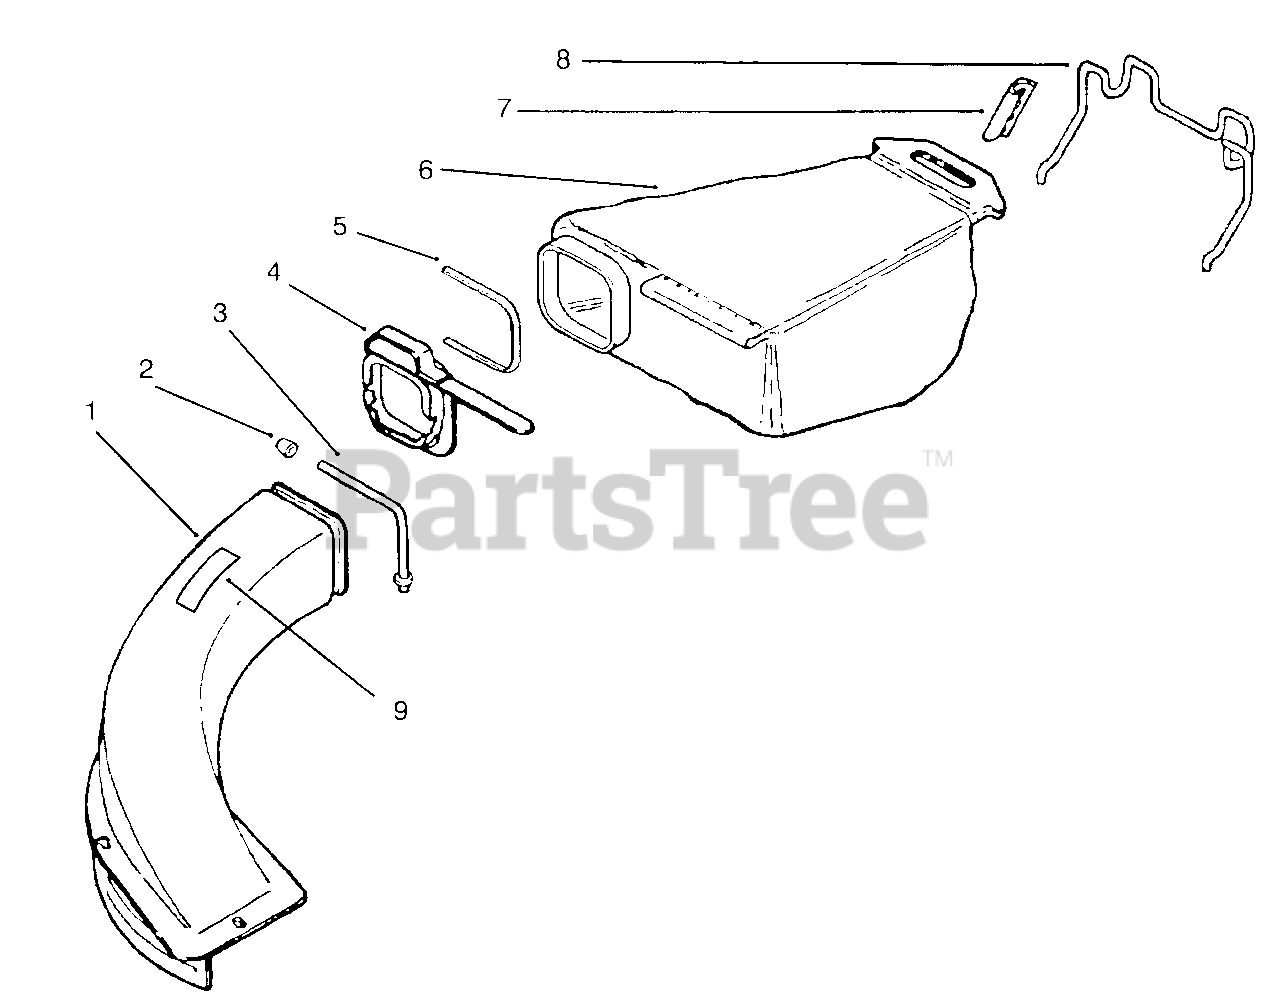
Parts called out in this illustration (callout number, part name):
1	Chute & Support Assembly (Incl. Ref.# 2,3 & 9)
2	Nut-Cap
3	Chute Support
4	Adaptor Assembly
5	Tie Strap
7	Hanger Clamp
8	Wide Hanger
9	Decal-Danger
